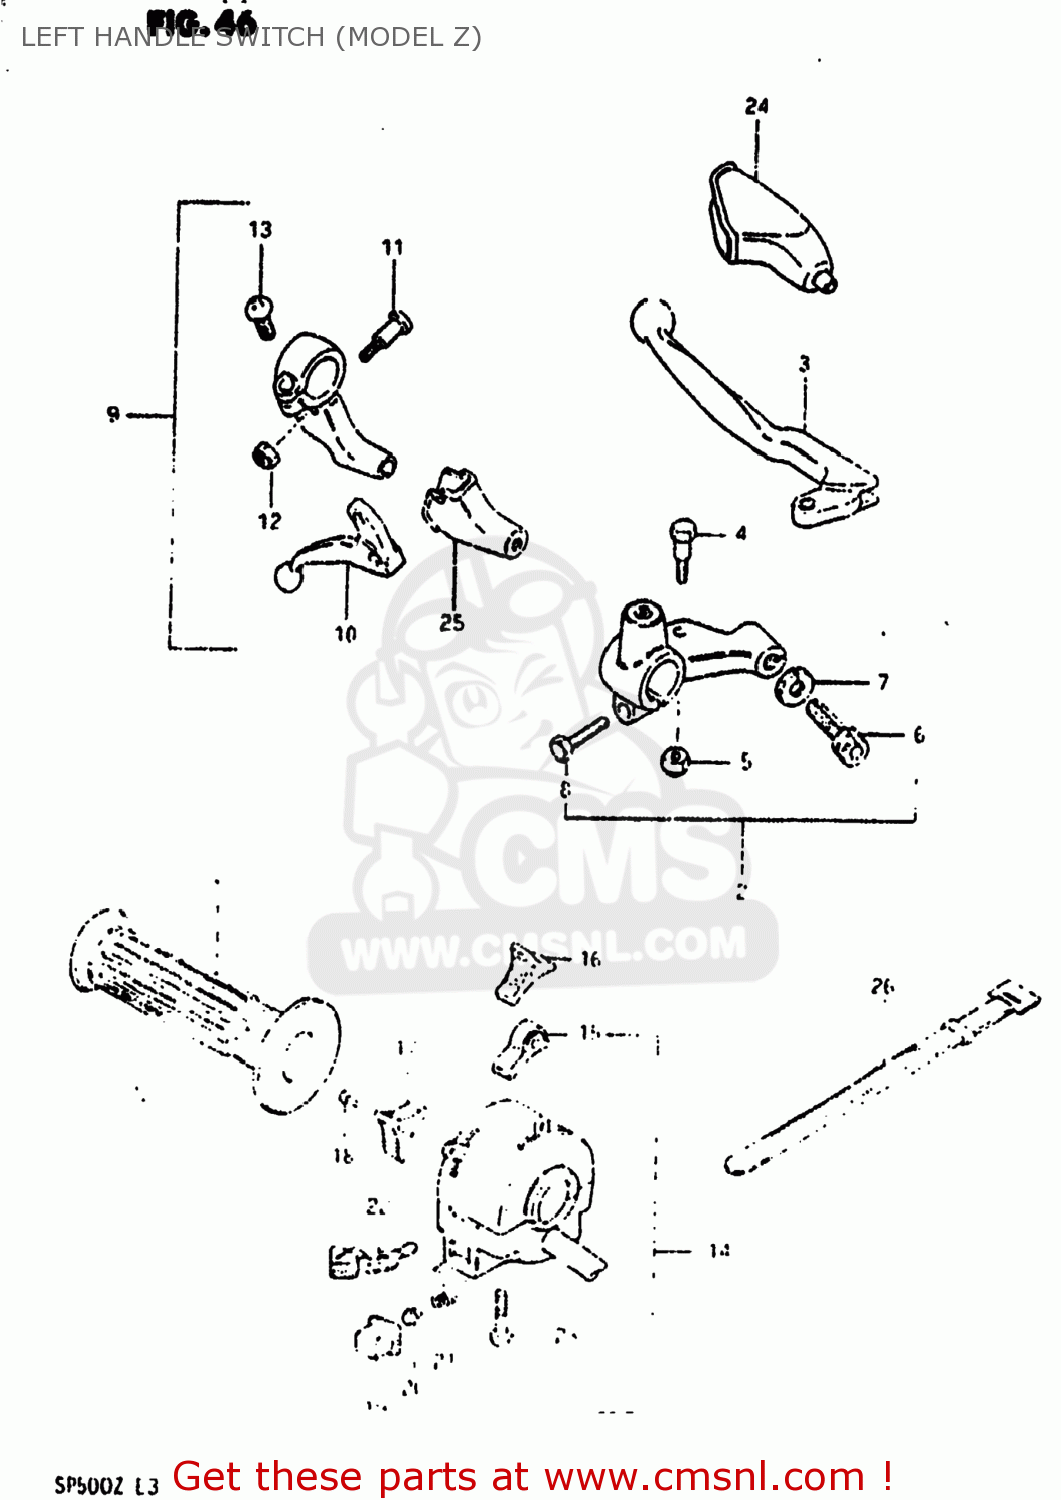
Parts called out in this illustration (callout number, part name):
1	GRIP,L
2	LEVER ASSY,CLUTCH
3	LEVER,CLUTCH
4	BOLT,LEVER
5	NUT 6MM
6	ADJUSTER,CABLE
7	NUT,CABLE ADJUSTER
8	BOLT,CLUTCH LEVER HOLDER
9	LEVER ASSEMBLY,DECOMPRESSION
10	LEVER,DECOMP
11	BOLT,LEVER
12	NUT,LEVER BOLT
13	SCREW
14	SWITCH ASSEMBLY,HANDLE,LEFT
15	KNOB,STOP
16	KNOB,LIGHTING SWITCH
17	KNOB,DIMMER SWITCH
18	SCREW
19	BUTTON,HORN
20	CONTACT
21	SPRING
22	KNOB,TURNSIGNAL
23	SCREW
24	COVER,CLUTCH LEVER
25	COVER,DECOMP LEVER DUST
26	CLAMP
